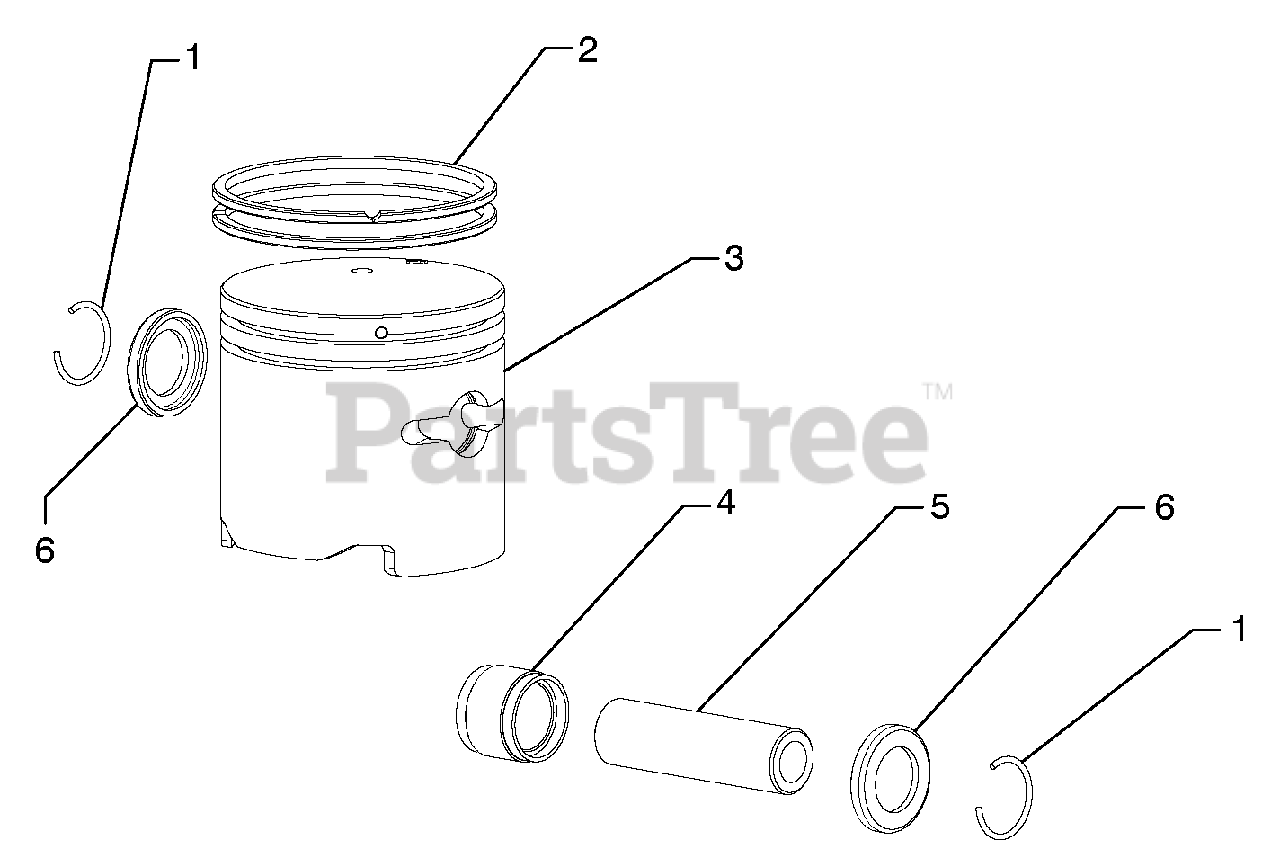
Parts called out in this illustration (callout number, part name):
1	Wrist Pin Clip Ring
2	Piston Ring
4	Needle Bearing (ID8 x 8.8)
5	Wrist Pin
